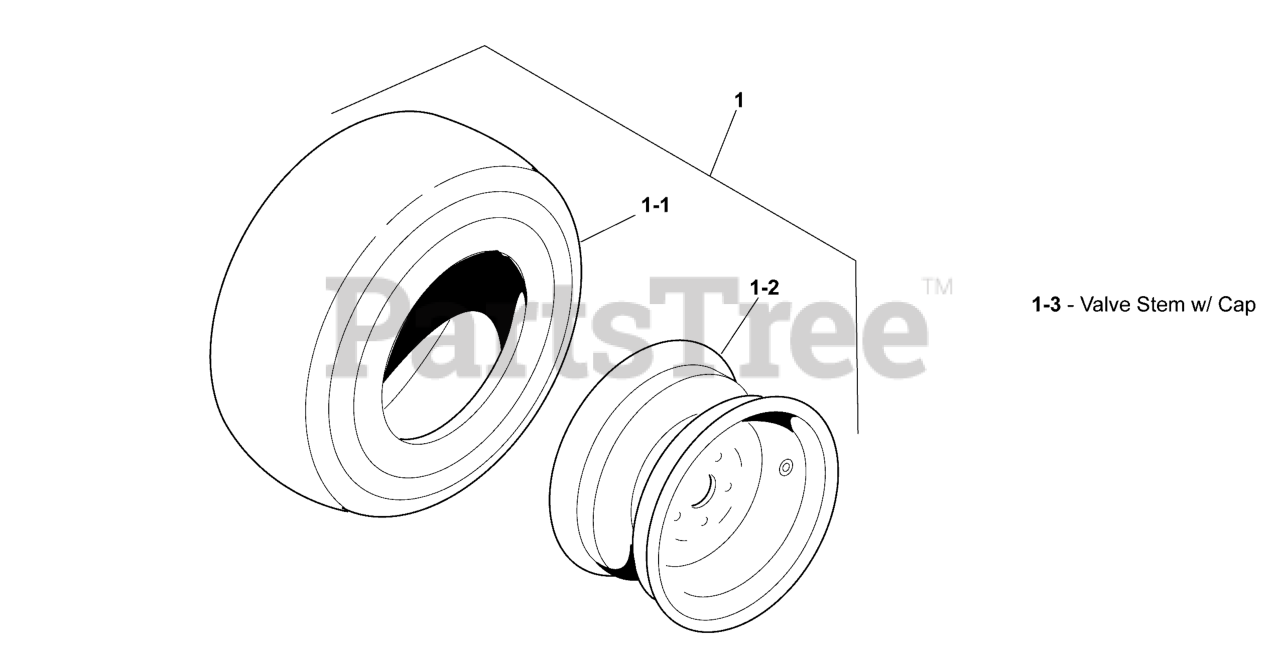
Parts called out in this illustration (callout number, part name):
1	TIRE, DEBRIS BLOWER, PAVEMENT TIRE
1-1	TIRE, 20.5 X 8.0-10, PAVEMENT, DEBRIS BLOWER
1-2	WHEEL
